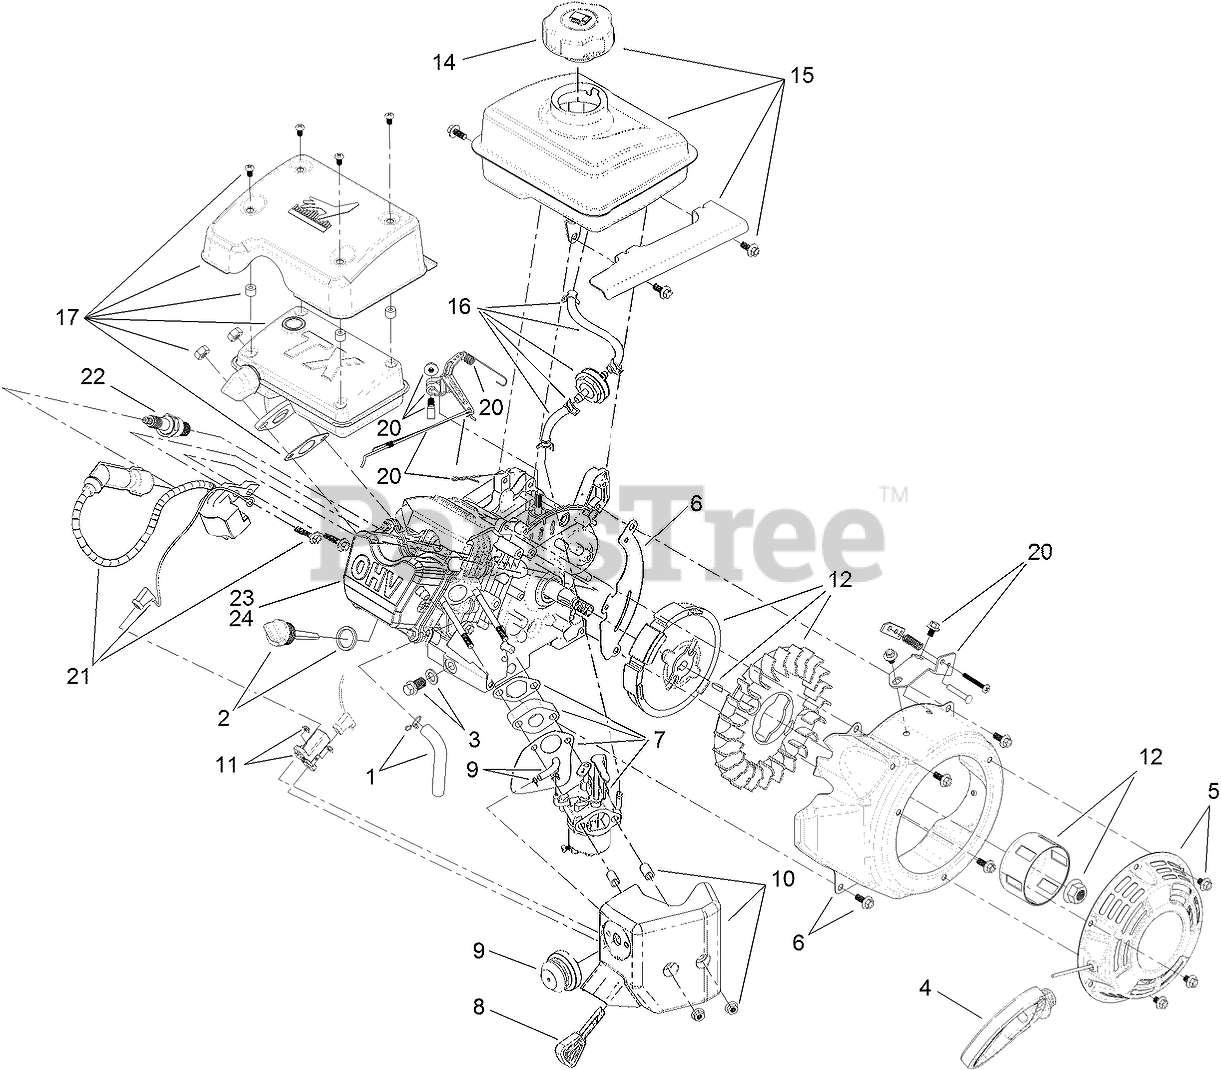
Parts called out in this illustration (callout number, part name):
1	BREATHER TUBE KIT
2	DIPSTICK AND O-RING KIT
3	DRAIN PLUG KIT
4	MITTEN GRIP KIT
5	RECOIL ASM KIT
6	BLOWER SHROUD KIT
7	COMPLETE CARB SERVICE KIT
8	KEY AND LANYARD KIT
9	PRIMER BULB KIT
10	HEATER BOX KIT
11	SWITCH KIT
12	FLYWHEEL AND FAN KIT
14	FUEL CAP ASM KIT
15	FUEL TANK, CAP AND HARDWARE KIT
16	FUEL LINE, FILTER AND CLAMP KIT
17	MUFFLER KIT
20	GOVERNOR ARM, SPRING, LINK, HARDWARE KIT
21	IGNITION KIT
22	SPARK PLUG
23	GASKET-COVER, VALVE
24	VALVE COVER ASM
